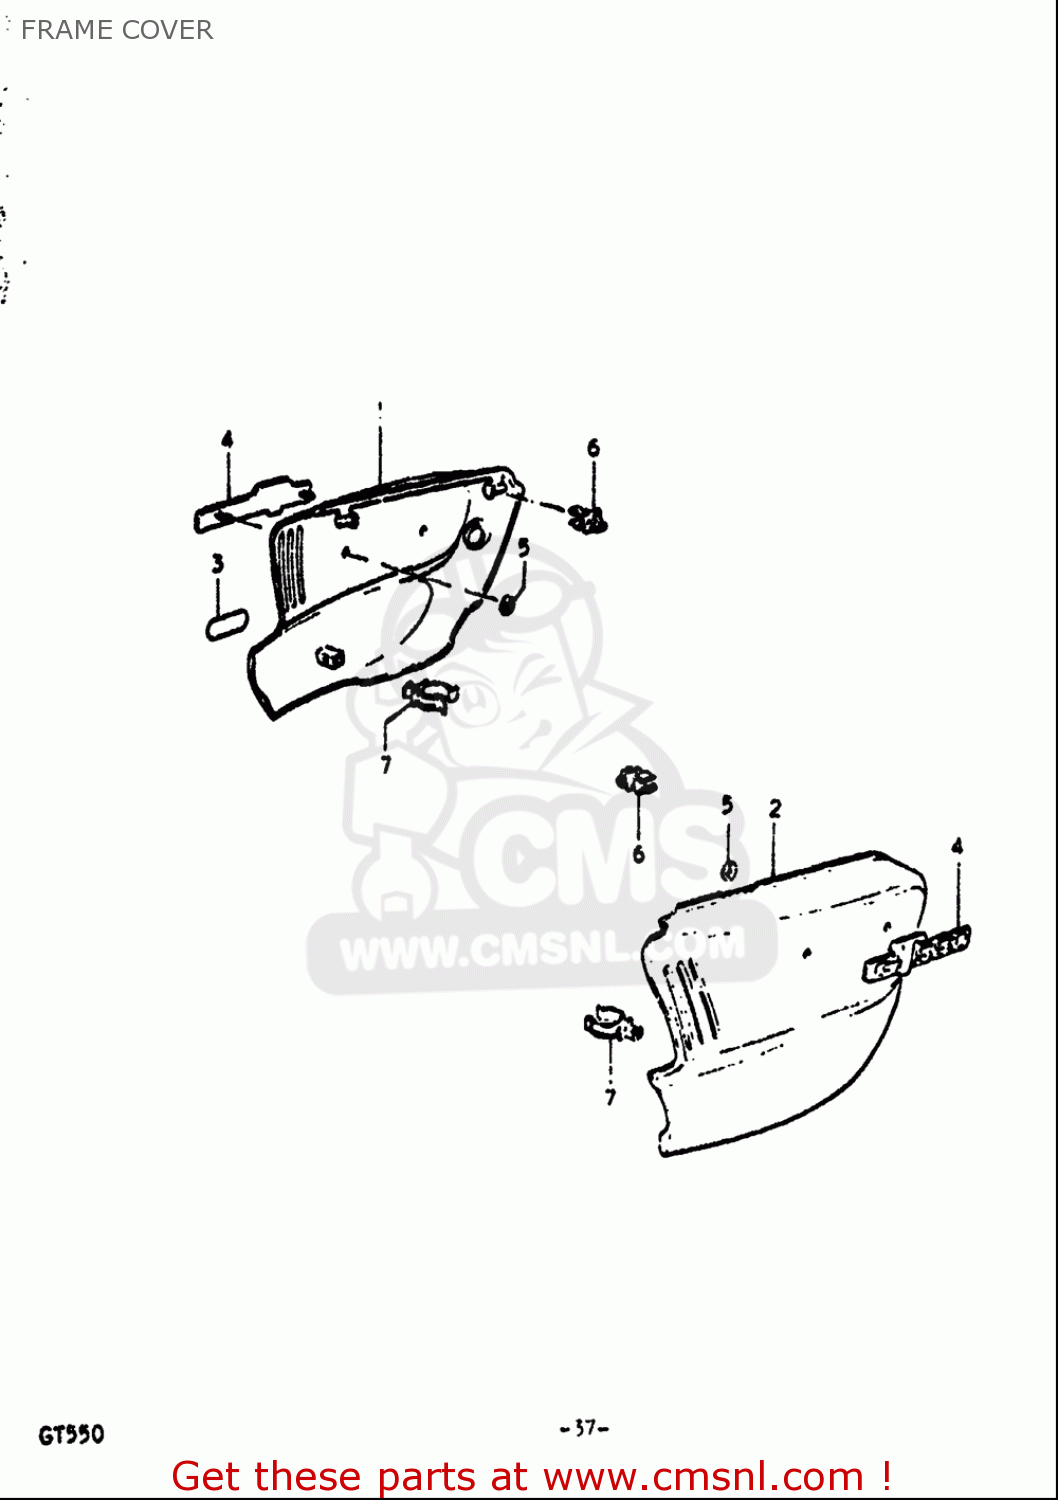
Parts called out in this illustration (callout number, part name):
1	FRAME,COVER,RIGHT
2	COVER,FRAME,LEFT
3	EMBLEM,CCIS
4	EMBLEM,FRAME COVER,R
5	NUT
6	CLAMP
